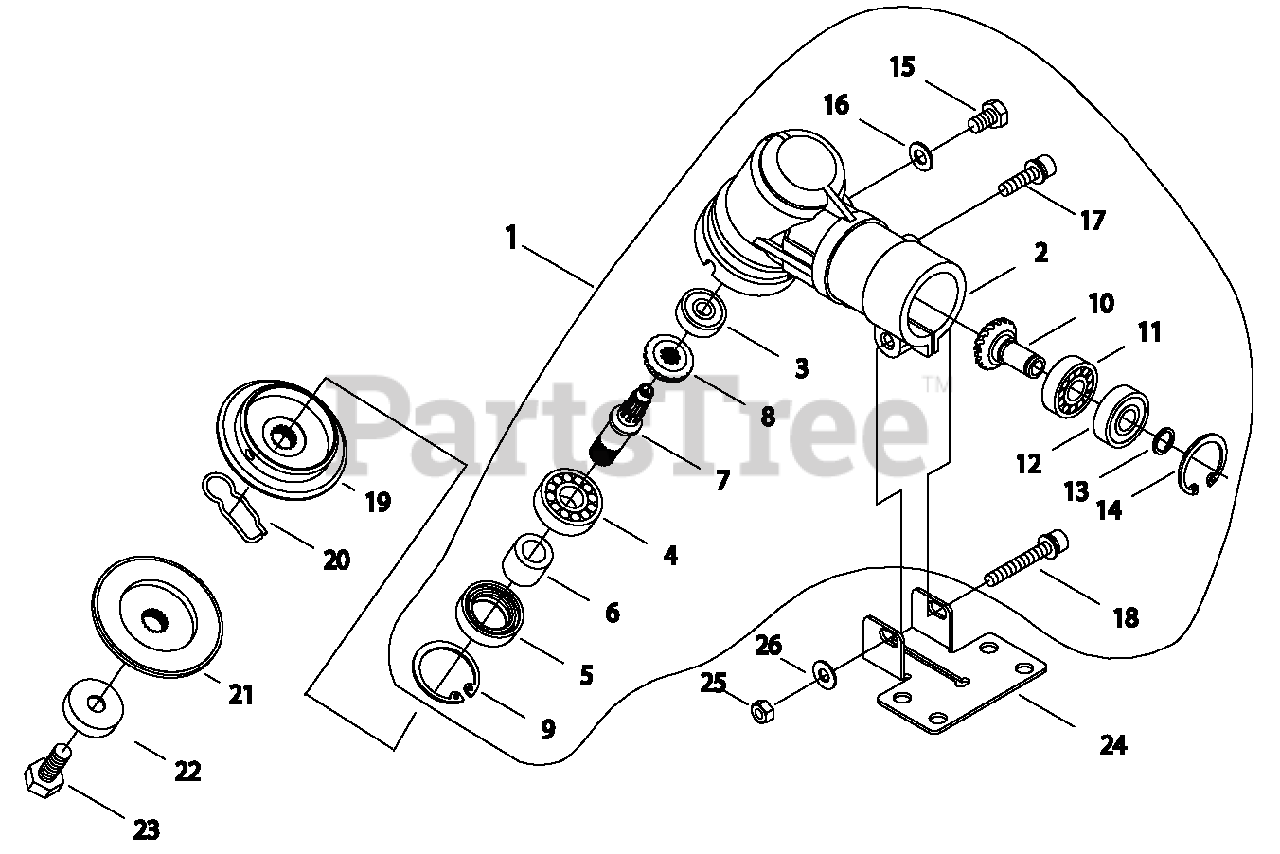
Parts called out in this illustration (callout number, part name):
1	GEAR CASE ASSY
2	HOUSING, GEAR CASE
3	BEARING, BALL 6000DDU
4	BEARING, BALL 6202
5	SEAL, OIL
6	COLLAR
7	SHAFT, GEAR
8	GEAR, BEVEL
9	RING, SNAP Ø35
10	PINION ASSY, BEVEL
11	BEARING, BALL 6001
12	BEARING, BALL 6001ZZ
13	RING, SNAP Ø12
14	RING, SNAP Ø28
15	BOLT M6×10
16	WASHER
17	BOLT M6×14
18	BOLT M6×40
19	PLATE, ADAPTOR - UPPER
20	PIN, SLIDE
21	PLATE, ADAPTOR - LOWER
22	GUARD, BOLT
23	BOLT 10×30
24	CLAMP, LOWER
25	NUT, HEX M6
26	WASHER
